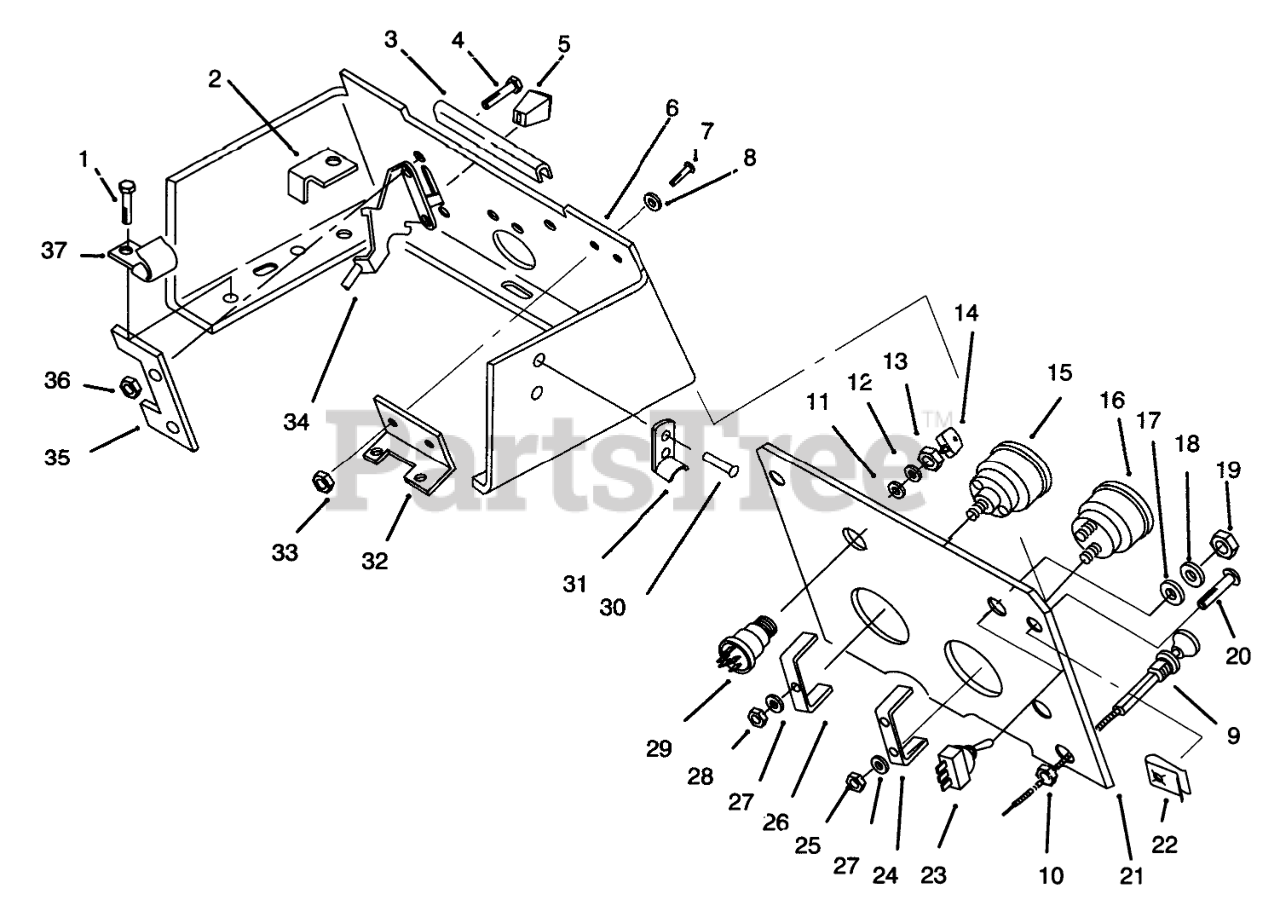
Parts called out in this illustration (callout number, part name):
1	Bolt
2	STOP-PTO
3	EDGING-CONSOLE
4	SCRW-PHC
6	CONSOLE B
7	SCREW-PAN
8	Washer-Lock
9	CONTROL-CHOKE
10	NUT-HEX PALNUT
11	Washer
12	LOCKWASHER
14	KEY-IGNITION
15	Meter-Hour (Incl. Ref. #27-28)
16	Meter-Volt (Incl. Ref. #24-25)
17	WASHER
18	TAB-WASHER
20	SCREW-PPH
21	Plate-Hood Stand
22	CLIP
23	Switch-Light (Incl. Ref. #17-19)
24	CLAMP-MOUNTING
25	HEX NUT 10-32 E.S.
26	CLAMP-HOUR METER
27	WASHER-LOCK
28	NUT-HEX
29	Switch-Ignition (Incl. Ref. #11-13)
30	POPRIVET 1/8X 1/8 BK
31	KEEPER-LATCH
32	BRACKET
33	Nut
34	CONTROL-THROTTLE
35	Washer
36	Nut
37	J-CLIP
